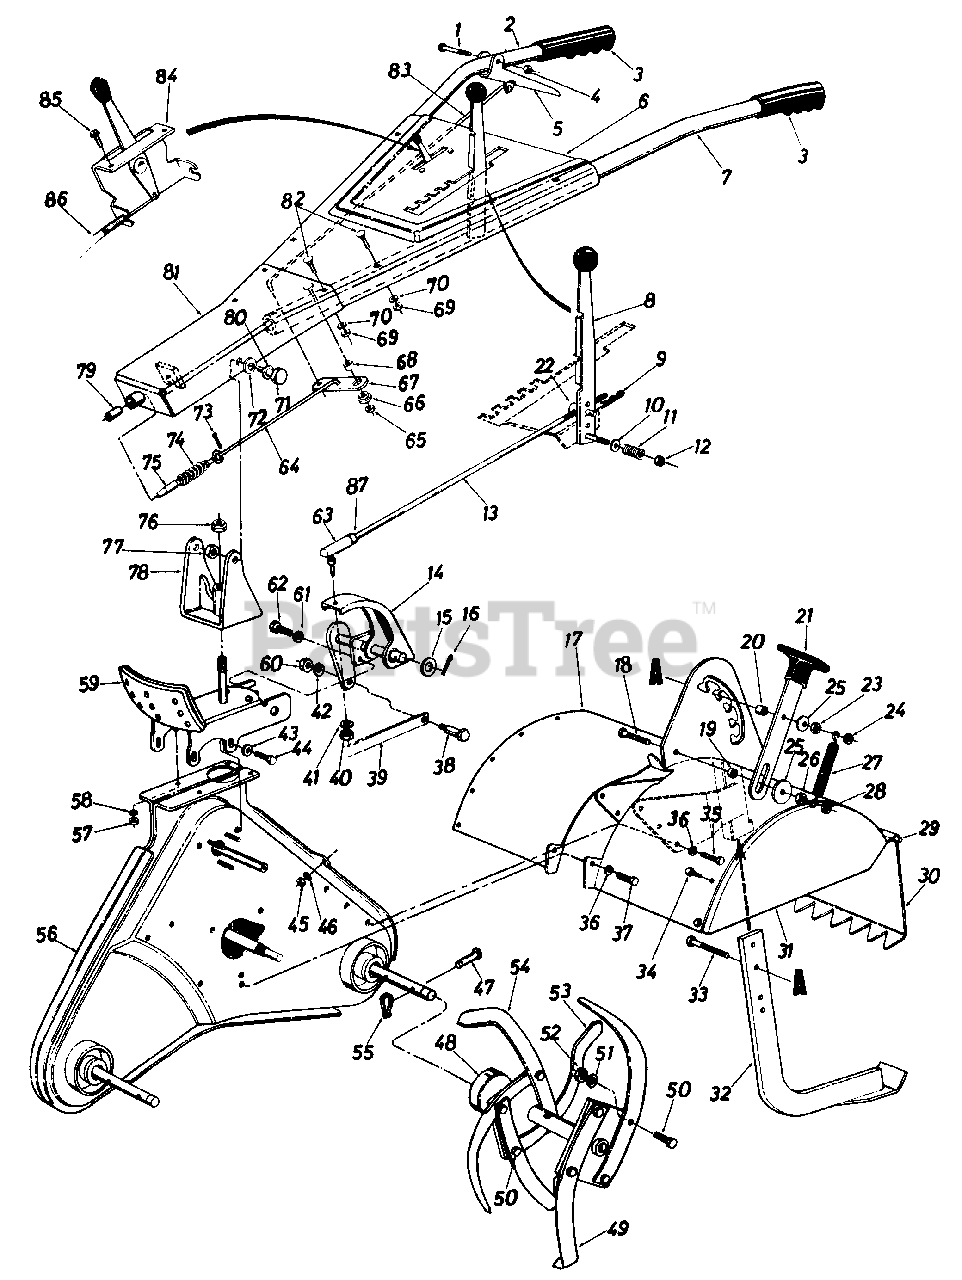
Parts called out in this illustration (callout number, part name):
1	Hex Bolt 1/4-20 x 1.75" Lg.
2	Handle - R.H.
3	Grip
4	Hex Cent. L-Nut 1/4-20 Thd.
5	Clutch Grip
6	Handle Panel Ass'y.
7	Handle - L.H.
8	Clutch Handle Ass'y.
9	Hairpin Cotter
10	Belleville Wash. .38" I.D.
11	Compression Spring .88" O.D. x .81" Lg.
12	Hex Cent. L-Nut 3/8-24 Thd.
13	Gear Shift Rod
14	Pivot Horn Ass'y.
15	Fl-Wash. .630 I.D. x 1.0" O.D. x .063
16	Cotter Pin 1/8" Dia. x .75" Lg.
17	Tine Shield Ass'y.
18	Hex Bolt 3/8-16 x 1.75" Lg.
19	Spacer .38 I.D. x .50 O.D. x .18 Lg.
20	Spacer .38 I.D. x .50 O.D. x .38 Lg.
21	Depth Bar Handle Ass'y. w/Knob
22	Ferrule
23	Hex Nut 3/8-16 Thd.
24	Hex Ins. L-Nut 3/8-16 Thd.
25	Fl-Wash .38 I.D. x 1.50 O.D. x .13
26	Hex Nut 3/8-16 Thd.
27	Spring - Depth Bar
28	Hex Ins. L-Nut 3/8-16 Thd.
29	Hinge Rod
30	Tine Shield Hinge Flap Ass'y.
31	Side Cover Tine Shield - L.H.
32	Depth/Drag Bar Ass'y.
33	Hex Bolt 3/8-16 x 1.75" Lg.
34	Hex Wash. Hd. Self-Tap Scr. 1/4-20 x .50" Lg.
35	Hex Wash. Hd. Self-Tap Scr.
36	L-Wash. 3/8" I.D.
37	Hex Wash. Hd. Self-Tap Scr.
38	Shoulder Bolt .50" Dia. x .25" Lg.
39	Control Bracket
40	Hex Ins. L-Nut 3/8-24 Thd.
41	L-Wash. 3/8" I.D.
42	L-Wash. 3/8" I.D.
43	Belleville Wash.
44	Hex Wash. Hd. Self-Tap Scr.
45	Hex Nut 3/8-24 Thd.
46	L-Wash. 3/8" Scr.
47	Clevis Pin
48	Tine Adapter Ass'y.
49	L.H. Tine Ass'y. Comp.
50	Hex Bolt 3/8-24 x 1.00" Lg.
51	L-Wash. 3/8" I.D.
52	Hex Nut 3/8-24 Thd.
53	Tine - R.H.
54	Tine - L.H.
55	Hairpin Cotter
56	Chain Case Ass'y. Comp.
57	Hex Nut 5/16-18 Thd.
58	L-Wash. 5/16" I.D.
59	Handle Positioner Ass'y.
60	Hex Ins. L-Nut 3/8-16 Thd.
61	L-Wash. 5/16" I.D.
62	Hex Wash. Hd. Self-Tap Scr.
63	Rod End 3/8-24 Thd.
64	Lower Handle Control Rod
65	Hex Nut 5/16-18 Thd.
66	Pivot Handle Brg.
67	Pivot Handle Link
68	Bushing Wash.
69	Hex Nut 5/16-18 Thd.
70	L-Wash. 5/16" I.D.
71	Shld. Bolt .500" Dia. x .660
72	Belleville Wash. .505" I.D. x 1.00" O.D.
73	Cotter Pin 1/8" Dia. x .75" Lg.
74	Compression Spring
75	Locking Pin
76	Hex Ins. L-Nut 5/8-16 Thd.
77	Hex Top L-Nut 3/8-16 Thd.
78	Pivot Brkt. Ass'y.
79	Sleeve Brg. .50" I.D. x .62" O.D. x 1.12" Lg.
80	Fl-Wash. .50" I.D. x 1.00" O.D. x .090
81	Handle Mtg. Brkt. Ass'y.
82	Carriage Bolt 5/16-18 x 1.75" Lg.
83	Handle Lock Rod
84	Throttle Control Ass'y. Comp.
85	Hex Wash. Hd. Tap Scr. #8 x .50" Lg.
86	Conduit and Wire 63.5" Lg.
87	Hex Jam Nut 3/8-24 Thd.
